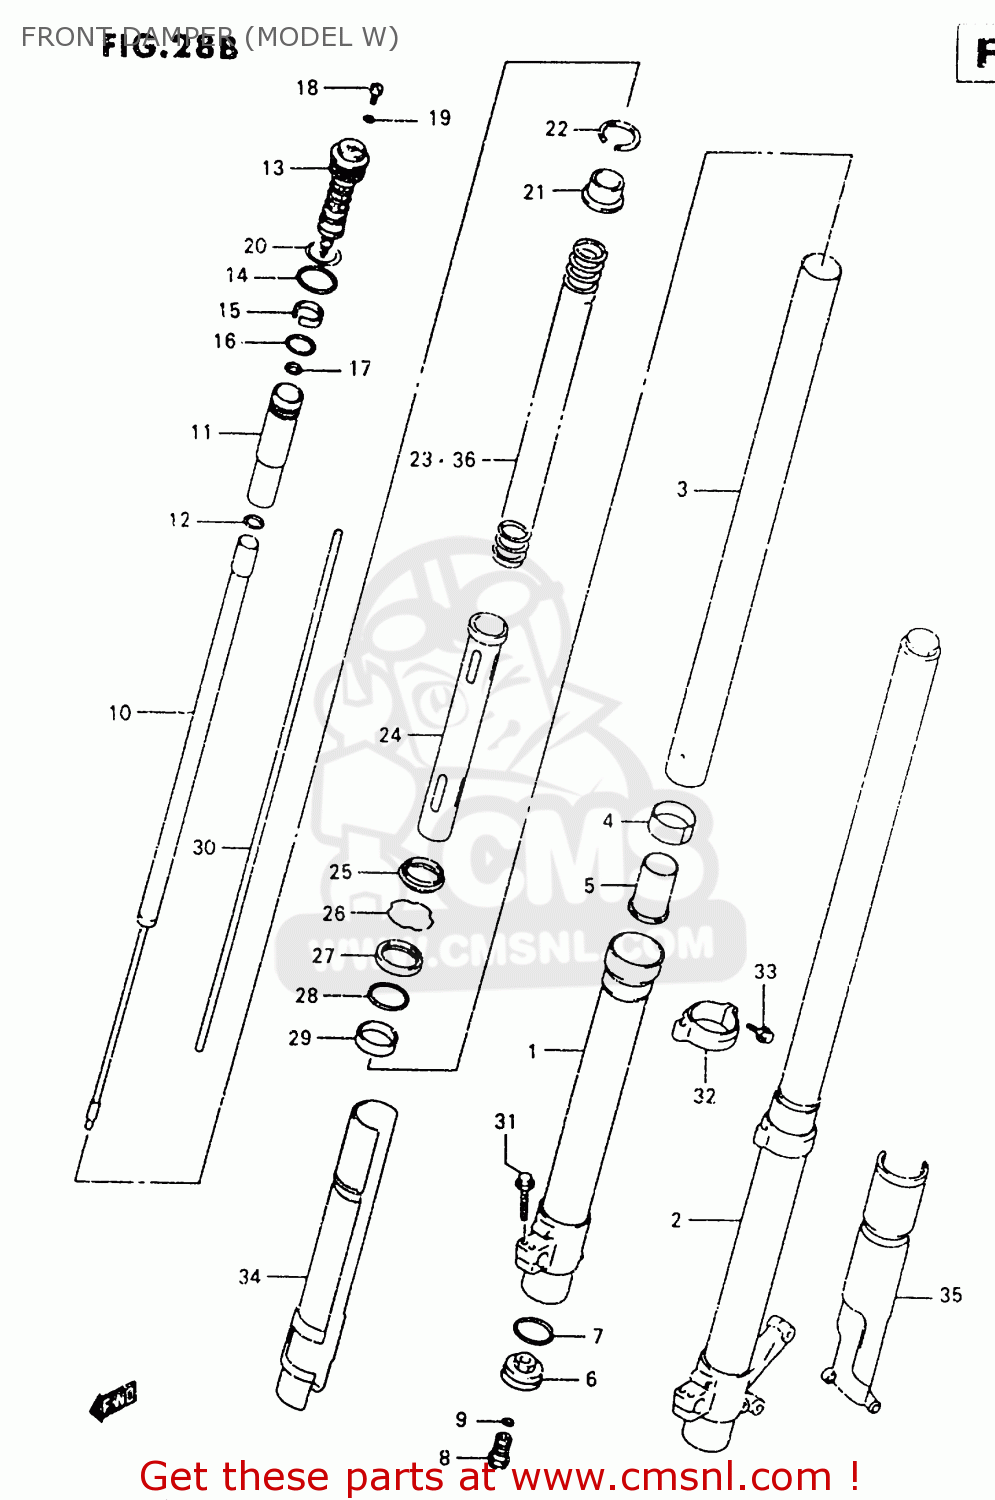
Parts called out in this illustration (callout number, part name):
1	TUBE,OUTER,R
2	TUBE,OUTER,LEFT
3	TUBE,INNER
4	BUSH,SLIDE
5	PIECE,OIL LOCK
6	PLATE,END
7	O RING
8	BOLT,CTR
9	O RING,CTR BOLT
10	ROD,FRONT DAMPER
11	TANK,SUB
12	O-RING
13	BOLT,FORK
14	O RING
15	BUSHING,SLIDE
16	O RING
17	O RING
18	BOLT,PLUG
19	O RING,PLUG
20	O RING
21	SPRING,STOPPER
22	RING,STOPPER
23	SPRING,FRONT (K=0.40)
24	COLLAR,SPRING
25	SEAL,DUST
26	RING,STOPPER
27	SEAL,OIL
28	SPACER,SEAL
29	BUSH,GUIDE
30	ROD,PUSH
31	BOLT,HANDLE HOLDER(8X35)
32	GUIDE,FR PROTECTOR,R
33	BOLT
34	PROTECTOR,OUTER TUBE,R
35	PROTECTOR,OUTER TUBE,L
36	SPRING,FRONT (K=0.38)
